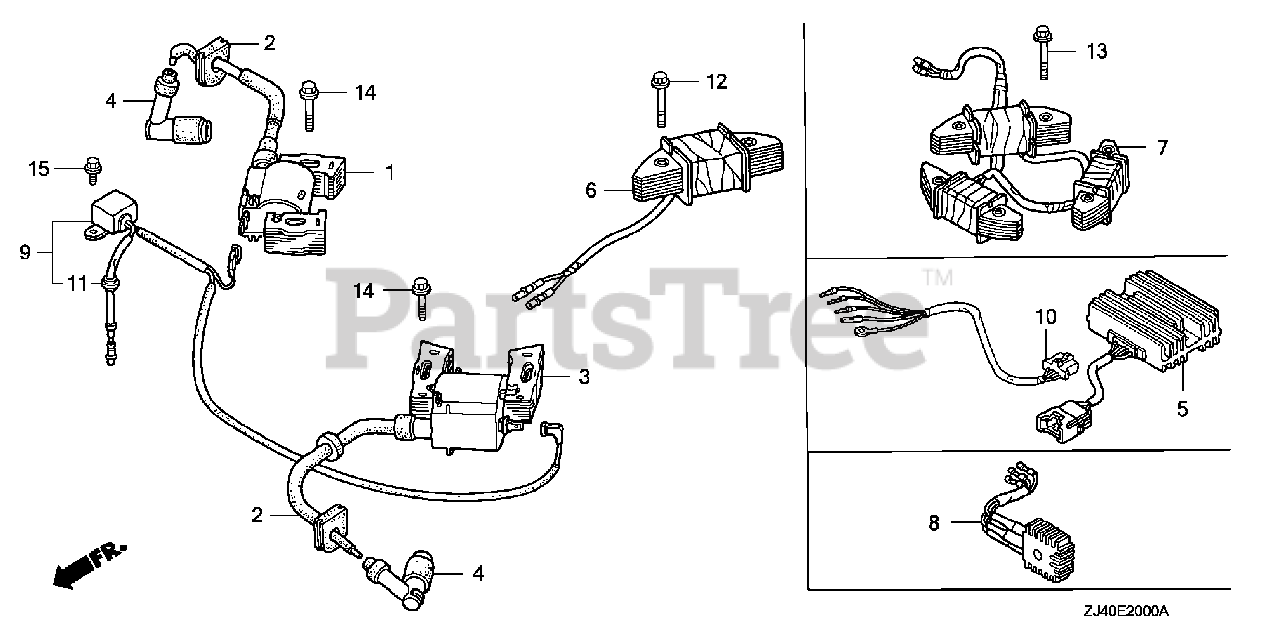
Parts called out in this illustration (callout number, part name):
1	COIL ASSY., IGNITION
2	GROMMET, IGNITION WIRE
3	COIL ASSY., IGNITION
4	CAP ASSY., NOISE SUPPRESSOR
6	COIL ASSY., CHARGE (12V/3A)
8	RECTIFIER ASSY. (10A)
9	DIODE ASSY., ENGINE STOP
11	GROMMET, TOOL
12	BOLT, FLANGE (6X35) (CT200)
14	BOLT, FLANGE (6X25) (CT200)
15	BOLT, FLANGE (6X8)
